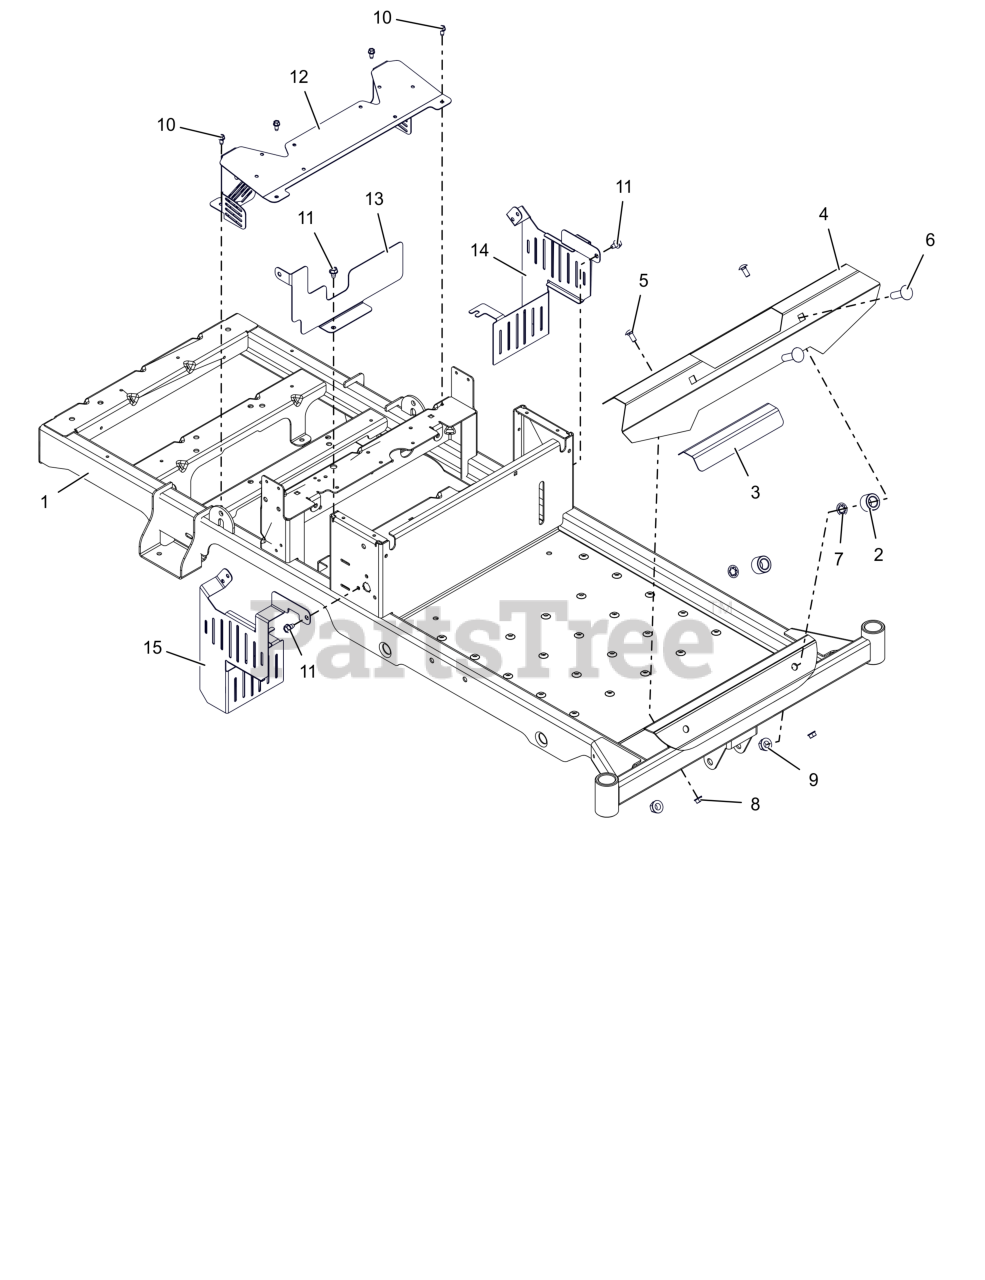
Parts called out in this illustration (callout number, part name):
1	KIT- EDGE FRAME W/DECALS
2	TUBE, UPPER CONTROL PIVOT
3	GRIP, STEP
4	FOOTREST, (ORANGE)
5	BLT, RHSSN.31-18X.750 G5 ZCC
6	BLT,RHSN .50-13X1.75 G5 ZCC
7	NUT-PUSH, .50
8	NUT,LK-CTR-FLG .31-18 GF ZCC
9	NUT-LK-CTR-FLG .500-13 GG ZCC
10	SCR-TAP .25-20X.50 HWH ZCC
11	SCR,TAP .312-18X.50 HWH TR ZCC
12	PLATE, FAN GUARD,CE
13	MUFFLER, LONCIN 635CC
14	SHIELD, LOWER TRANSAXLE LH CE
15	SHIELD, LOWER TRANSAXLE RH CE
